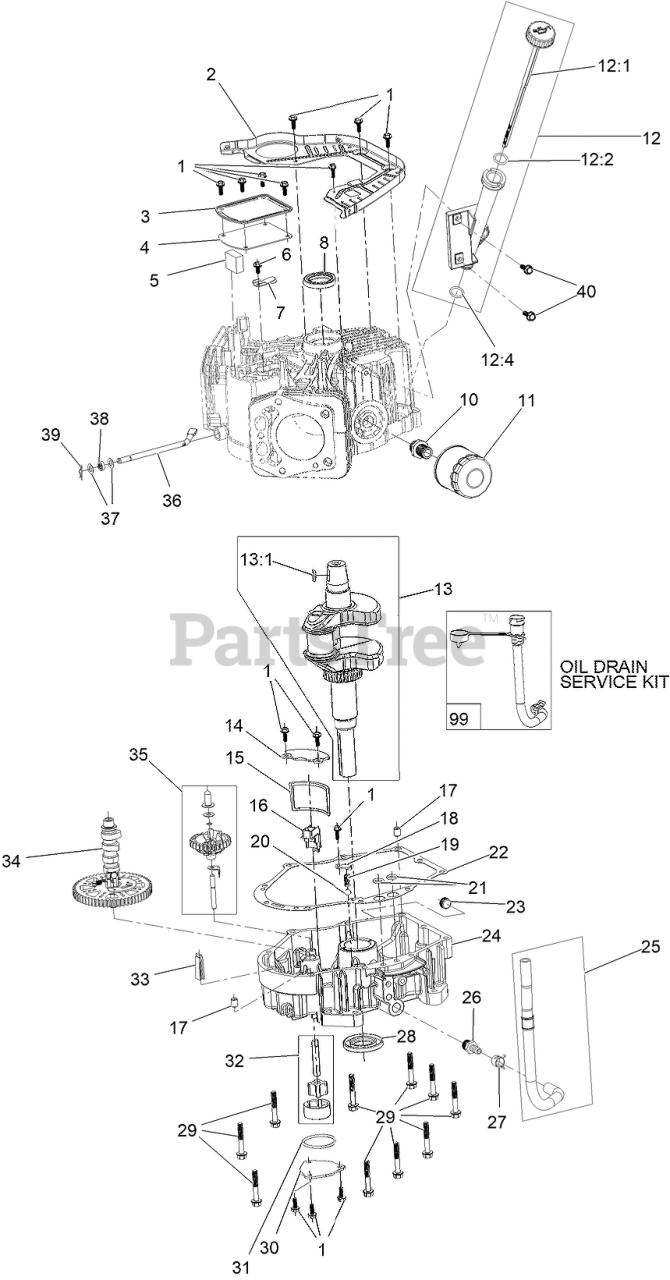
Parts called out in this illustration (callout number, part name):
1	SCREW-HHF
2	BAFFLE
3	COVER-BREATHER
4	GASKET-BREATHER
5	FILTER-BREATHER
6	SCREW-HHF
7	VALVE-BREATHER
8	SEAL-OIL
10	ADAPTOR-FILTER, OIL
11	FILTER-OIL
12	OIL TUBE ASM
12:1	DIPSTICK
12:2	O-RING
12:4	O-RING
13	CRANKSHAFT
13:1	KEY-WOODRUFF
14	COVER-SCREEN, OIL
15	SCREEN-OIL
16	RETAINER-SCREEN
17	PIN-DOWEL
18	PLATE-RETAINER
19	SPRING
20	VALVE-BALL
21	O-RING
22	GASKET-COVER, CRANKCASE
23	PLUG-DRAIN
24	COVER-CRANKCASE
25	OIL DRAIN HOSE ASM
26	FITTING-HOSE
27	CLAMP-HOSE
29	SCREW-HHF
30	COVER-OIL PUMP
31	O-RING
32	OIL PUMP ASM
33	DEFLECTOR-OIL, RUBBER
34	CAMSHAFT
35	GOVERNOR ASM
36	SHAFT-GOVERNOR
37	WASHER-PLAIN
38	SEAL-OIL
39	PIN-HAIR
40	SCREW-HHF
99	OIL DRAIN SERVICE KIT
